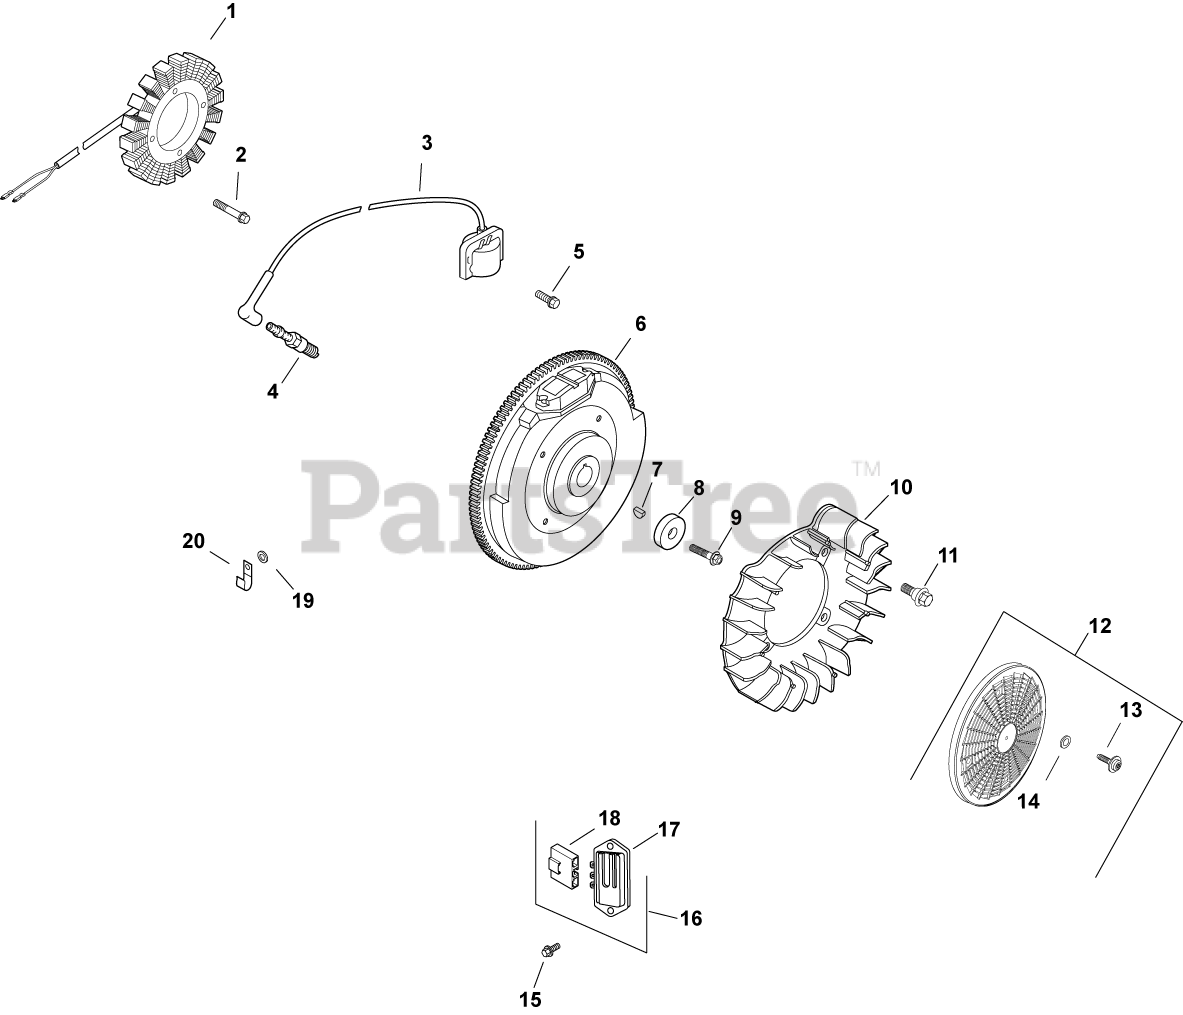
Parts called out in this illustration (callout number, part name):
1	KIT, 25 AMP STATOR ASSY.
2	SCREW, THD FROM M5X0.8X30
3	KIT, MODULE IGNTN (CDI FIXED)
4	PLUG, SPARK (STD)
5	SCREW, FLG THD FRM M5X.8X20-(#25086399S)
6	FLYWHEEL, PAINTED-USE 24 025 59-S
7	KEY, 3/16" X 5/8"
8	WASHER, FLAT 13/32"
9	SCREW, FLG M10X1.5X45 - (#25086361S)
10	FAN USE 24 755 253-S
11	BOLT, SHOULDER
12	KIT, GRASS SCREEN
13	SCREW, FLG SEMS M4X.7X25
14	WASHER, FLAT 3/16"
15	SCREW, HEX FLANGE HI-LO
16	KIT, FULL WAVE CONVERSION
17	REG/RECTIFIER (20/25 AMP)-USE 25 403 20-
18	CONNECTOR (1 CONTACT)
19	WASHER, FLAT 1/4" (O.D. 1/2")
20	CLIP, CABLE
